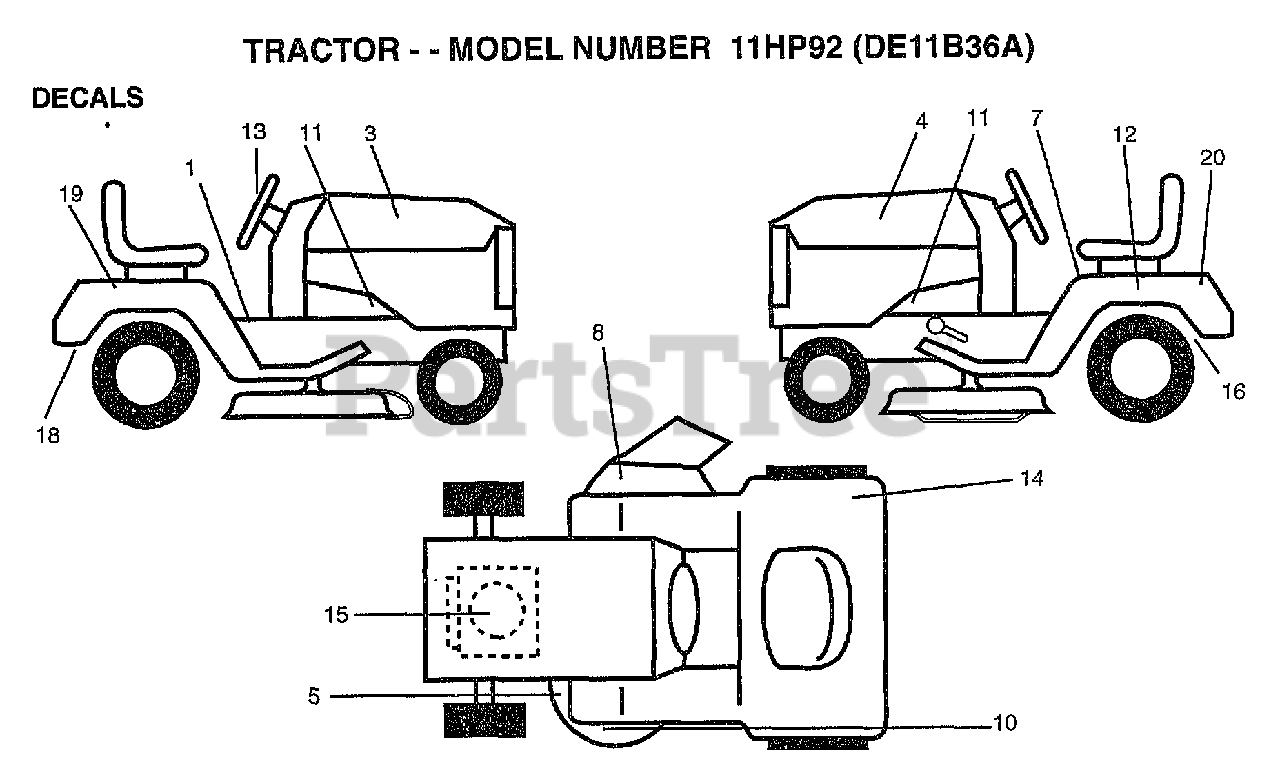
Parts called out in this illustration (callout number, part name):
1	DECAL CLUTCH/BRAK
3	DECAL.HOOD.RH
4	DECAL.HOOD.LH
5	DECAL.V.BELT
7	DECAL.READ.O.MANU
8	DECAL.DANGER.CUTF
10	DECAL.DECK.MOWER
11	"DECAL CHASSIS,HOT"
12	DECAL.BATRY.3-3908
13	DECAL.INST.STEERING
16	DECAL.DRAWBAR.LDL
18	DECAL.EURO.ST.CE.
19	DECAL.FENDER.RH
20	DECAL FENDER LH
